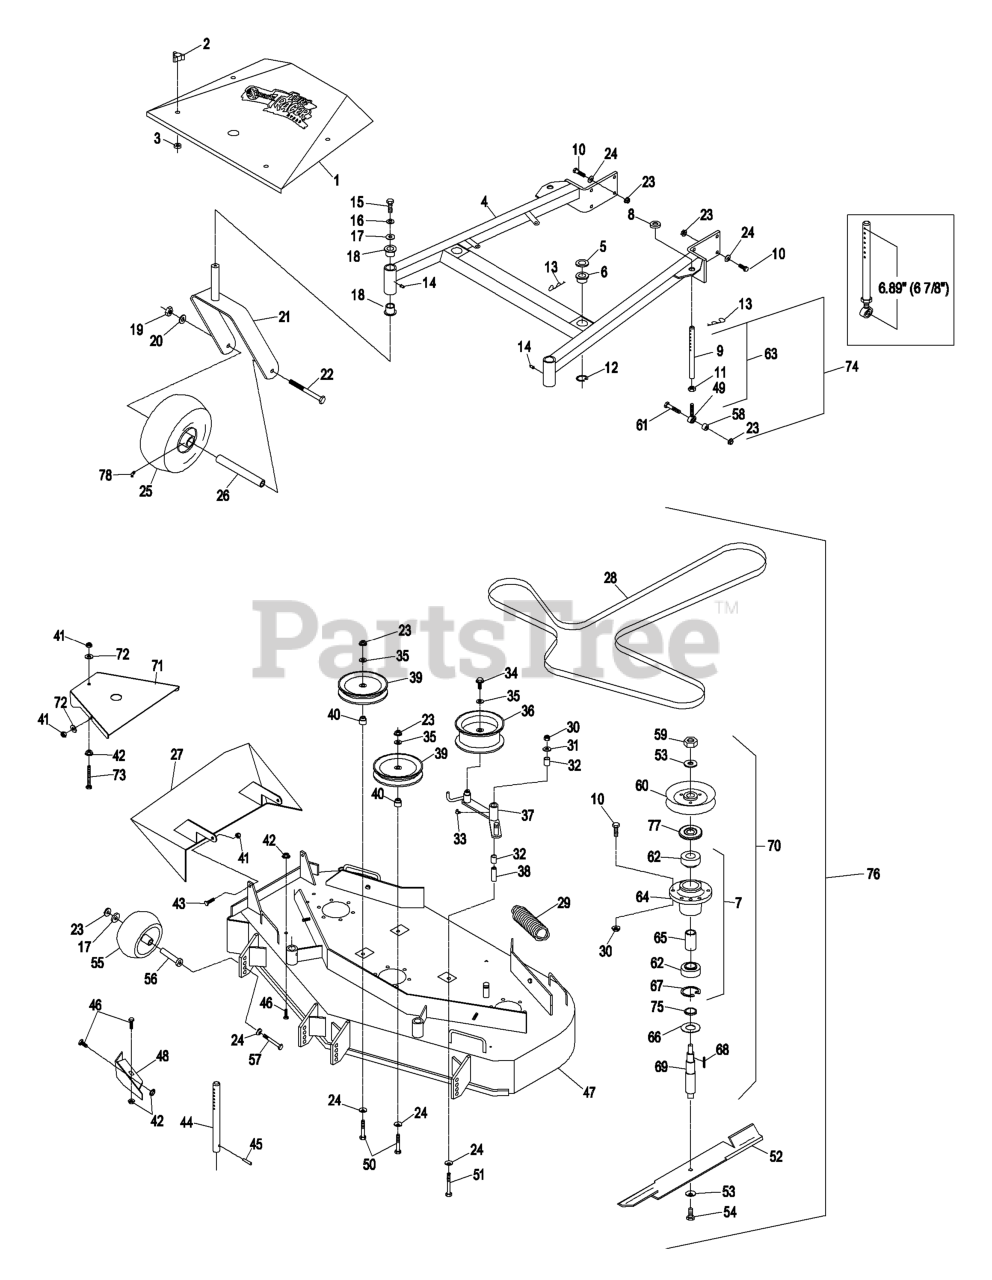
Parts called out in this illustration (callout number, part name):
2	KNOB-3 PRONG
4	DECK SUPPORT W/BSHGS 48"
5	SPACER-DECK SUPPORT
6	BUSHING-DECK
9	LINK,SUPPORT
10	SCREW-HH
11	NUT-HEX
12	RING-RETAINING
13	PIN,HAIR COTTER
14	FITTING-GREASE
15	SCREW-HH
16	WASHER-LOCK
18	BEARING-FLANGED
19	NUT-HH
20	WASHER-LOCK
22	SCREW-HH
23	NUT-HHF, WHIZ
24	WASHER-BELLEVILLE
26	SPACER FRONT CASTER
27	WLD,DISCHARGE CHUTE 36/48
28	BELT - V, B
30	NUT-LOCK, NI
31	WASHER-FLAT
32	SLEEVE-BEARING
33	FITTING-GREASE, 90 DEG
34	SCREW-HHF
35	WASHER-FLAT
38	BUSHING-PIVOT, IDLER
39	PULLEY-IDLER
40	BUSHING-IDLER
41	NUT-LOCK, NI
43	SCREW-HH
44	ROD,DECK SUPPORT
46	SCREW-HH
47	ASM,DECK W/DECALS TTHP/MH
49	BALLJOINT
50	SCREW-HH
51	SCREW-HH
53	WASHER-SPRING
54	SCREW-CAP
55	ROLLER-SCALP, ANTI
56	BUSHING-ROLLER
57	SCREW-HH
59	NUT-HEX
60	SHEAVE,W/HUB 5.72
61	SCREW-HH
62	BEARING
65	SPACER-BEARING
66	GUARD-BEARING, BOTTOM
67	RING-SNAP
68	KEY-RECTANGLE
69	SHAFT,SPINDLE
70	HOUSING,CUTTER COMPLETE
72	WASHER-FLAT
73	BOLT,TAP HH
75	SPACER-PULLEY/BEARING
76	Assembly,Cutting Deck Complete
77	GUARD-BEARING, TOP
78	FITTING-GREASE
79	KIT, SP CASTER WHEEL REPL
